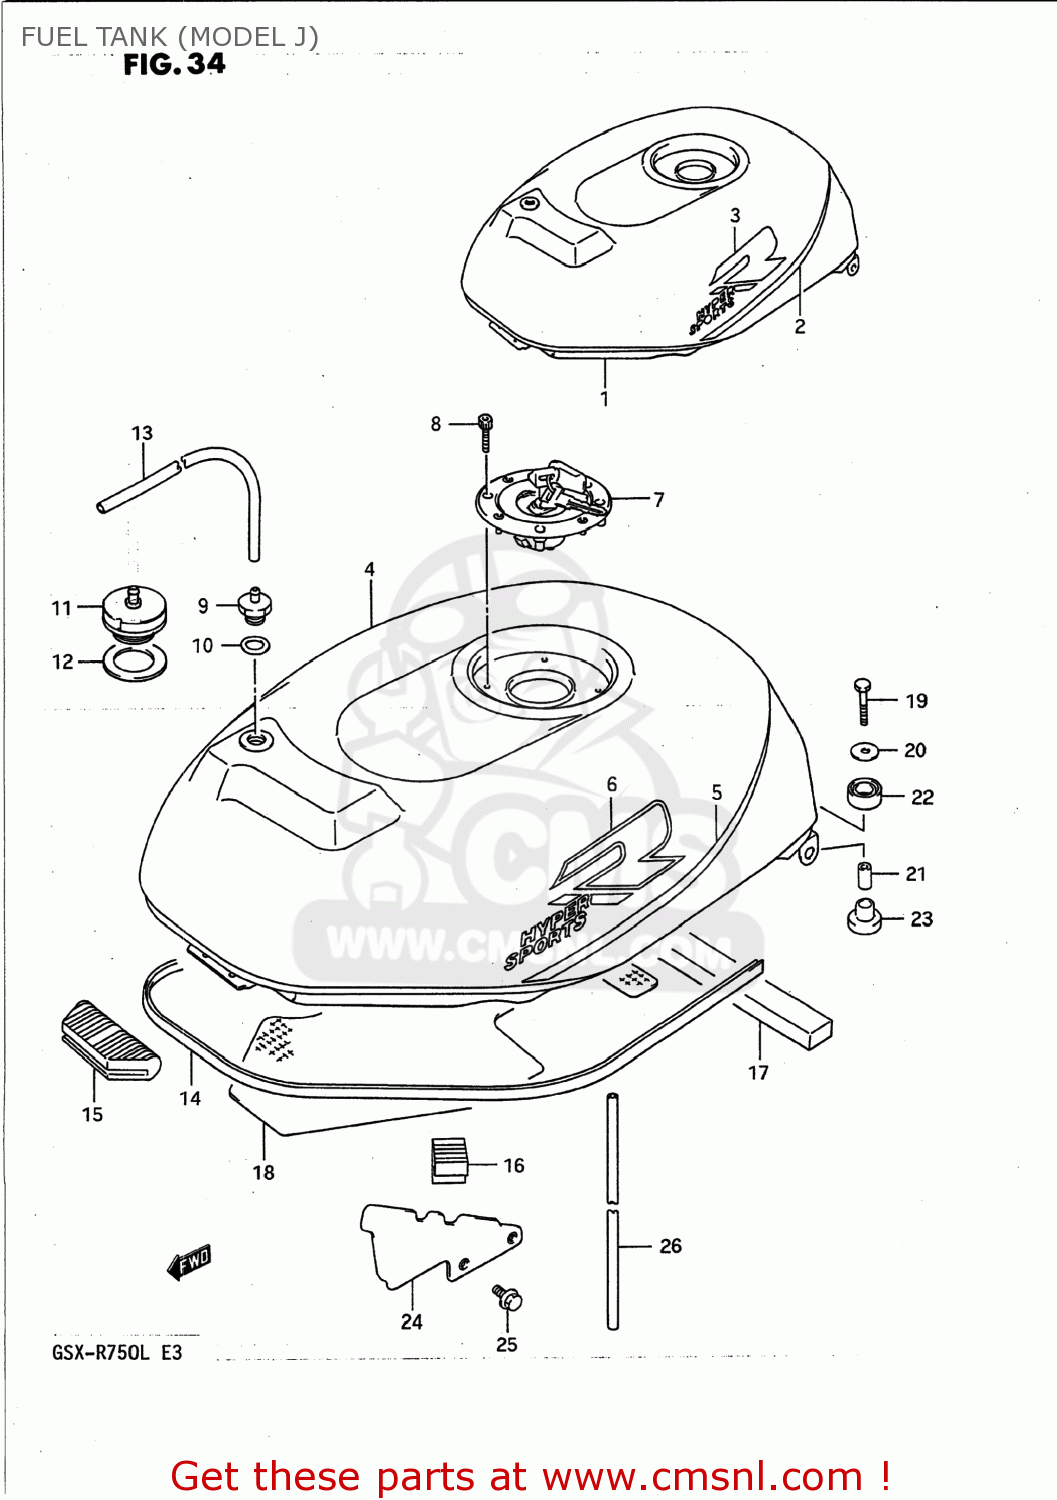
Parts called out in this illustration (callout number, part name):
1	TANK ASSEMBLY,FUEL
2	TAPE,FUEL TANK (BLUE)
3	EMBLEM,FUEL TANK
4	TANK ASSEMBLY,FUEL
5	TAPE,FUEL TANK STRIPE
6	EMBLEM,FUEL TANK
7	CAP SET,FUEL TANK
8	BOLT(5X20)
9	PLUG,FUEL TANK BREATHER
10	GASKET(12.5X20X2.5) (NAS)
11	(CA) VALVE,FUEL TANK BREATHER
12	GASKET 27X40X2.5 (NAS)
13	HOSE
14	MOLDING,FUEL TANK
15	CUSHION,FUEL TANK FR
16	CUSHION,FUEL TANK SIDE
17	CUSHION, AIR SEAL
18	HEAT SHIELD,FUEL TANK
19	BOLT ,6X35
20	WASHER (6.5X24X1.6)
21	SPACER
22	CUSHION
23	CUSHION
24	COVER,FRONT,LEFT
25	BOLT 6X20
26	HOSE
